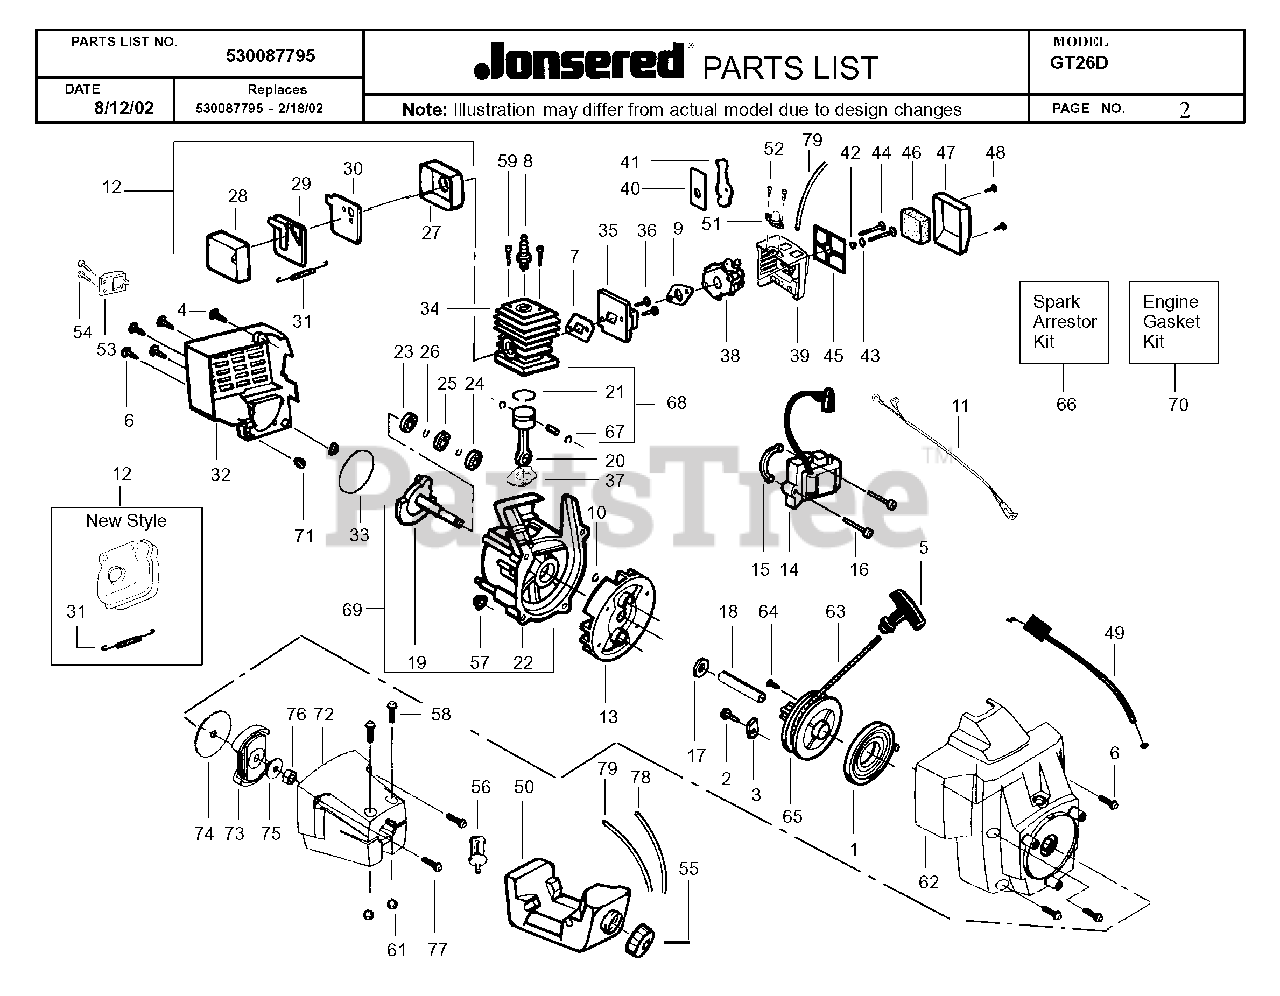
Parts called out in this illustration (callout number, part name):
1	STARTER SPRING
2	SCREW 8-16 X 9/16 (PLAS
5	HANDLE-STARTER
6	SCREW - SHROUD
7	GASKET - CYLINDER / CARB ADAPT
10	RETAINING RING
11	LEAD WIRE ASSEMBLY
13	FLYWHEEL
14	IGNITION MODULE
15	SPACER - IGNITION MODULE
18	DRIVE COUPLING
19	CRANKSHAFT ASSEMBLY
20	CONNECTING ROD ASSEMBLY
21	RING-PISTON
22	ASSY-CRANKCASE
23	BEARING
25	SEALING RING
27	MUFFLER BODY
28	MUFFLER COVER
33	GASKET, CRANKCASE
34	CYLINDER
36	SCREW - CARB. ADAPTOR
37	GASKET - CYLINDER
38	CARBURETOR
40	CHOKE PLATE
41	CHOKE SHUTTER
43	CHOKE SPACER
45	FILTER PLATE
46	AIR FILTER FOAM
47	AIR FILTER COVER
49	THROTTLE CABLE.
50	TANK UNIT
51	AIR PURGE BUBBLE
53	MUFFLER GUARD
54	SCREW-8-18 X 5/18(RECES
55	CAP ASSY W/ RETAINER
56	FUEL PICK-UP ASSY
57	CRANKCASE ISOLATOR
58	SCREW-10-24 X 1-3/8 (UN
61	LOCKNUT-HEX 10-24
65	STARTER PULLEY KIT
67	WRIST PIN RET.
70	GASKET KIT
71	SHROUD ISOLATOR
73	CLUTCH ASSEMBLY KIT
74	FRICTION DISC,CLUTCH 36/41
75	WASHER FLAT
77	SCREW-10-14 X 13/16 (PL
530069380	KIT-SPARK ARRESTOR (OLD STYLE)
530069989	MUFFLER (OLD STYLE)
530071309	KIT-MUFFLER (NEW STYLE)
